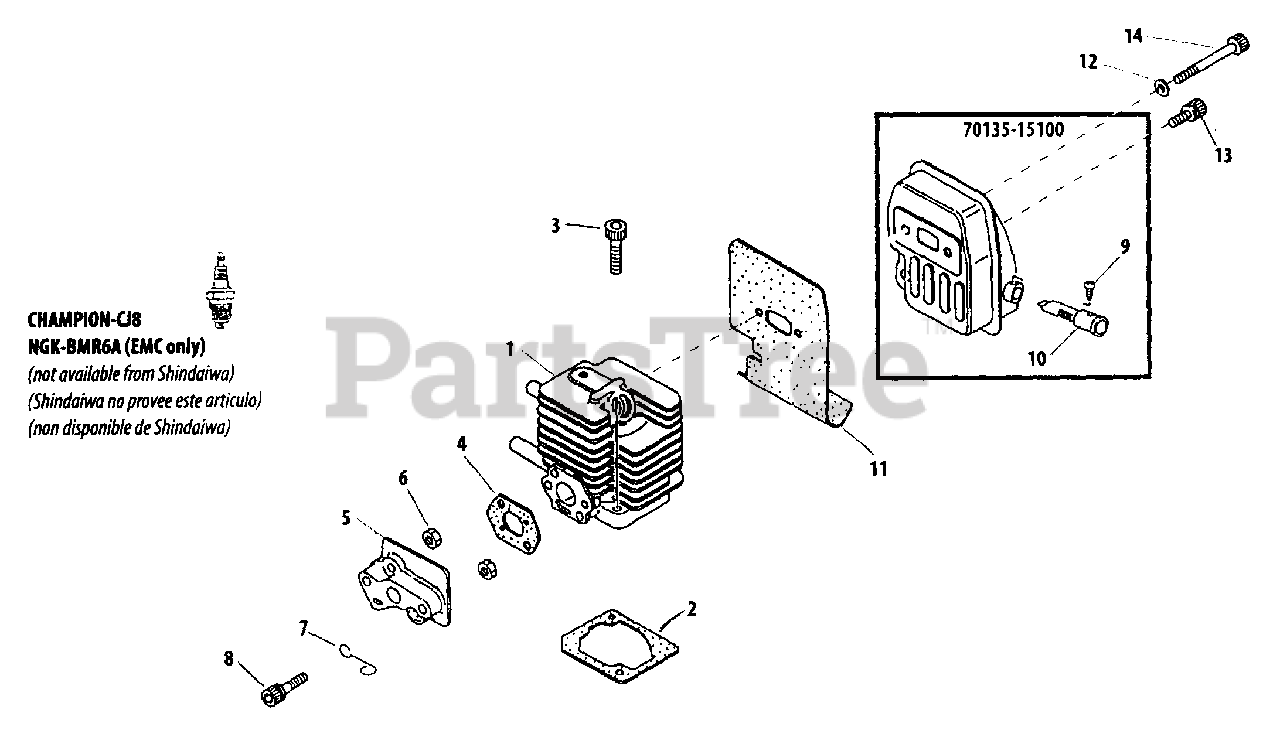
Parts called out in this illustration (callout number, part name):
1	CYLINDER
2	GASKET, CYLINDER
3	SCREW - 5X25
4	GASKET
5	INSULATOR
7	HOLDER, VENT
8	SCREW - 5X30
9	SCREW - 3X6
10	SCREEN, SPARK ARRESTOR
11	SHIELD, EXHAUST
12	WASHER - 5
13	SCREW - 5X12
14	SCREW - 5X50
70135-15100	MUFFLER ASSY
